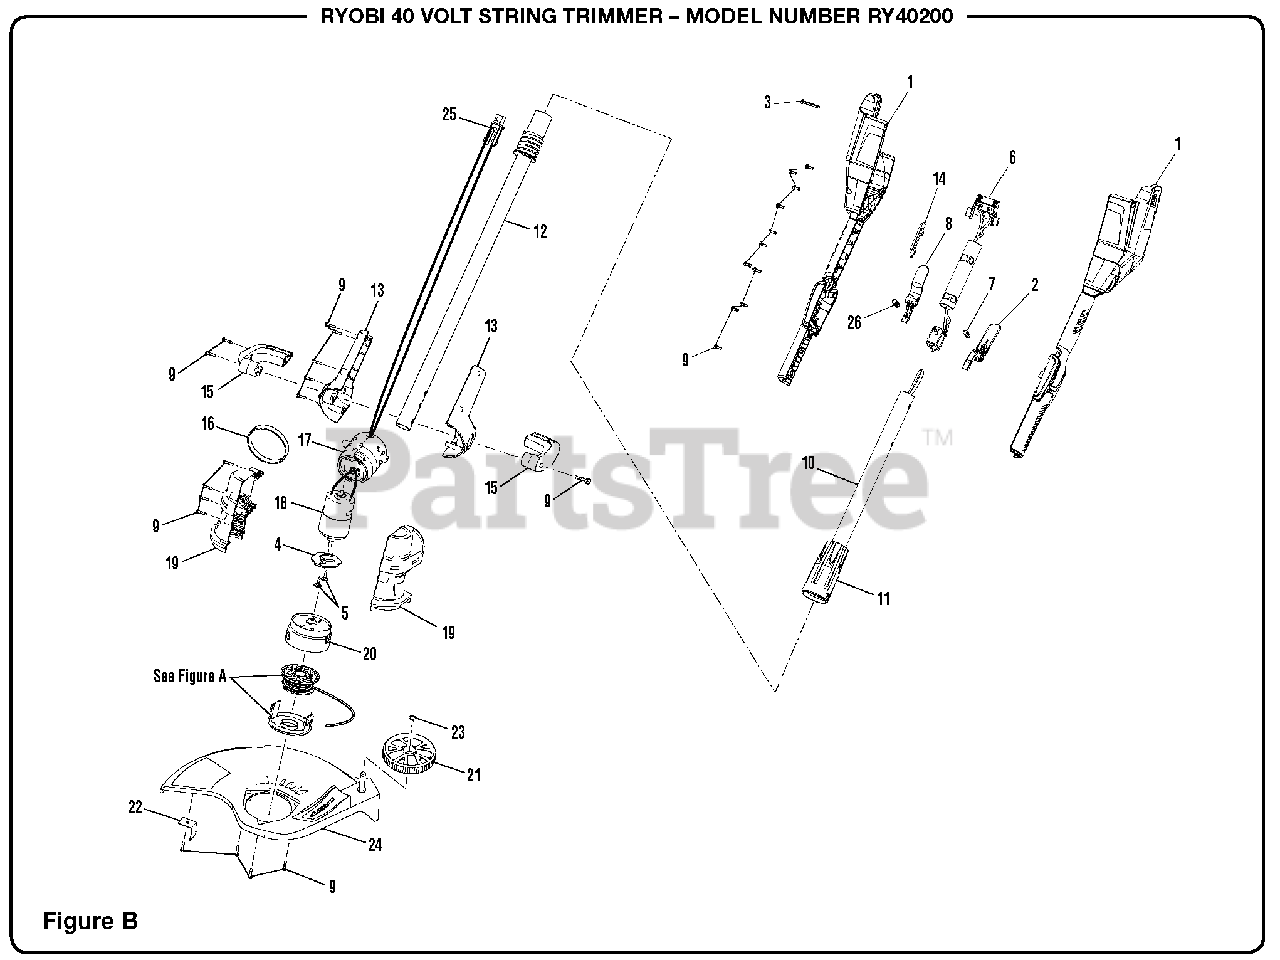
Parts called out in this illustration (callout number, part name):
1	40V Power Head Assembly
2	Adjustable Front Handle
3	Screw (M4 x 30 mm)
4	Motor Mounting Plate
5	Screw w/Washer
6	Data Label (Upper Boom)
7	Compression Spring
8	Lock-Out Button
9	Grass Deflector Assembly
10	Warning Icon Label (Power Head)
11	Slider Assembly
12	Lower Boom Assembly (Inc. Key No. 25)
13	Warning Icon Label (Boom)
14	Shoulder Strap Hook
15	Boom Warning Label
16	Coupler Ring
17	Pivot Assembly
18	Rotation Arrow Label
19	Compression Spring
22	Operator's Manual
23	Retaining Ring
25	Male Plug
